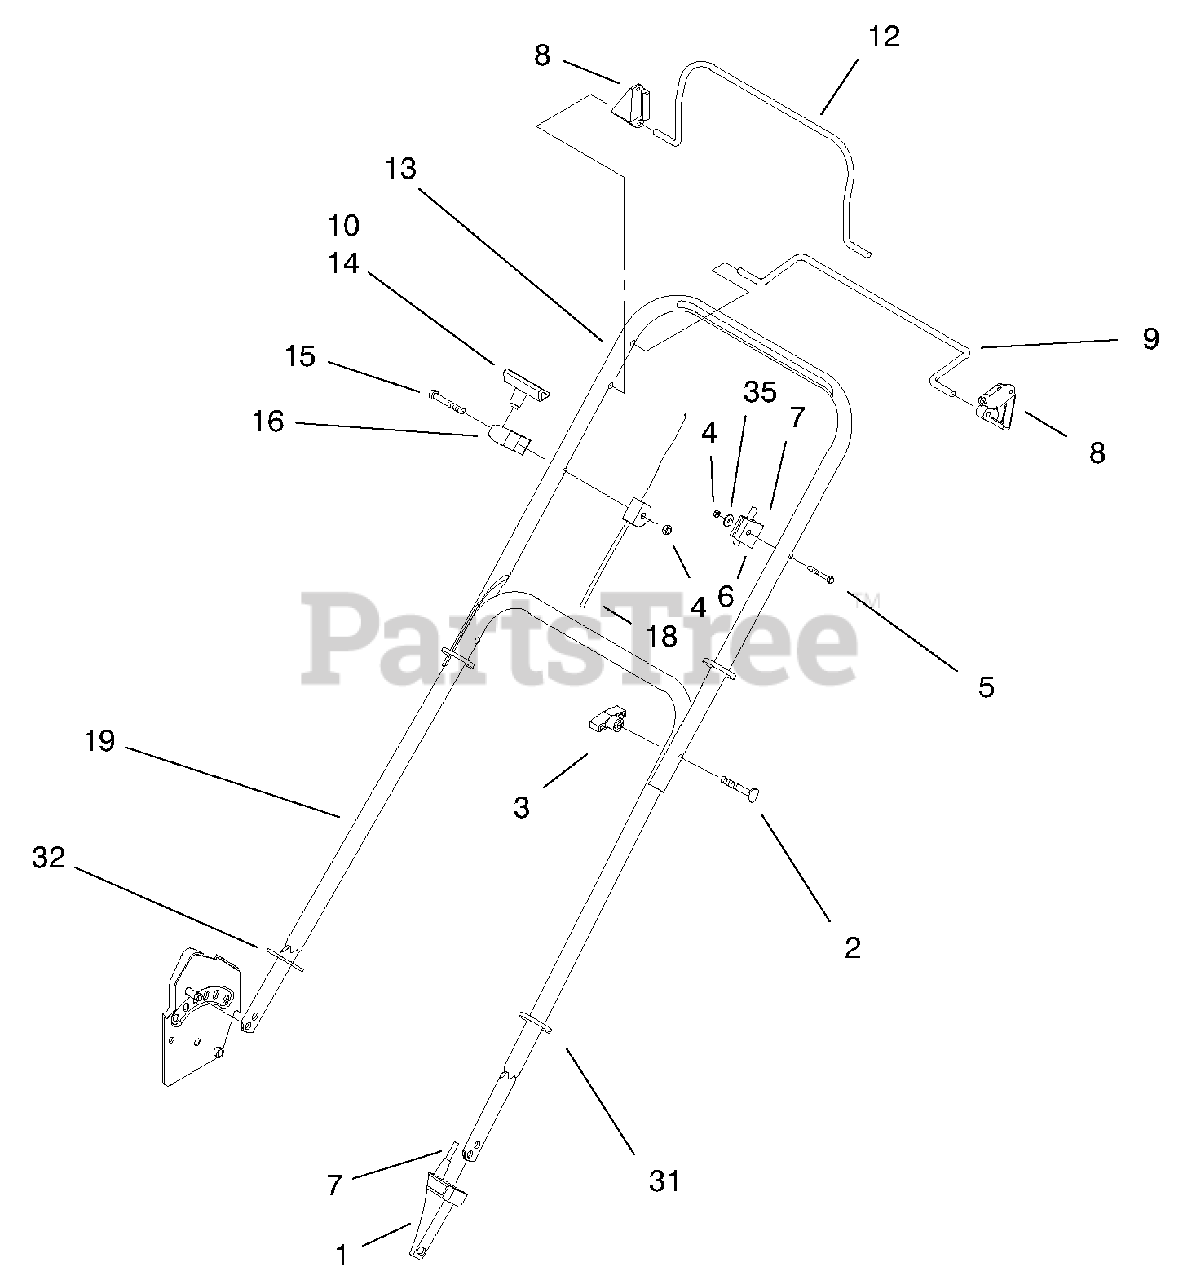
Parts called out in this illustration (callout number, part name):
1	Anchor-Cable
2	Screw-Handle
4	Nut-Lock
5	Screw-Handle
6	Anchor-Cable
7	Cable-Traction
8	Stop-Pivot
9	Bail-Sp Control
10	Staple-Handle
12	Bail-Flywheel Brake
13	Handle Section-Upper
14	Handle-Starter
16	Guide-Rope
18	ASM-Brake Cable
19	Handle Section-Lower
31	Tie Strap
32	Handle-Guard
35	Washer-Flat
